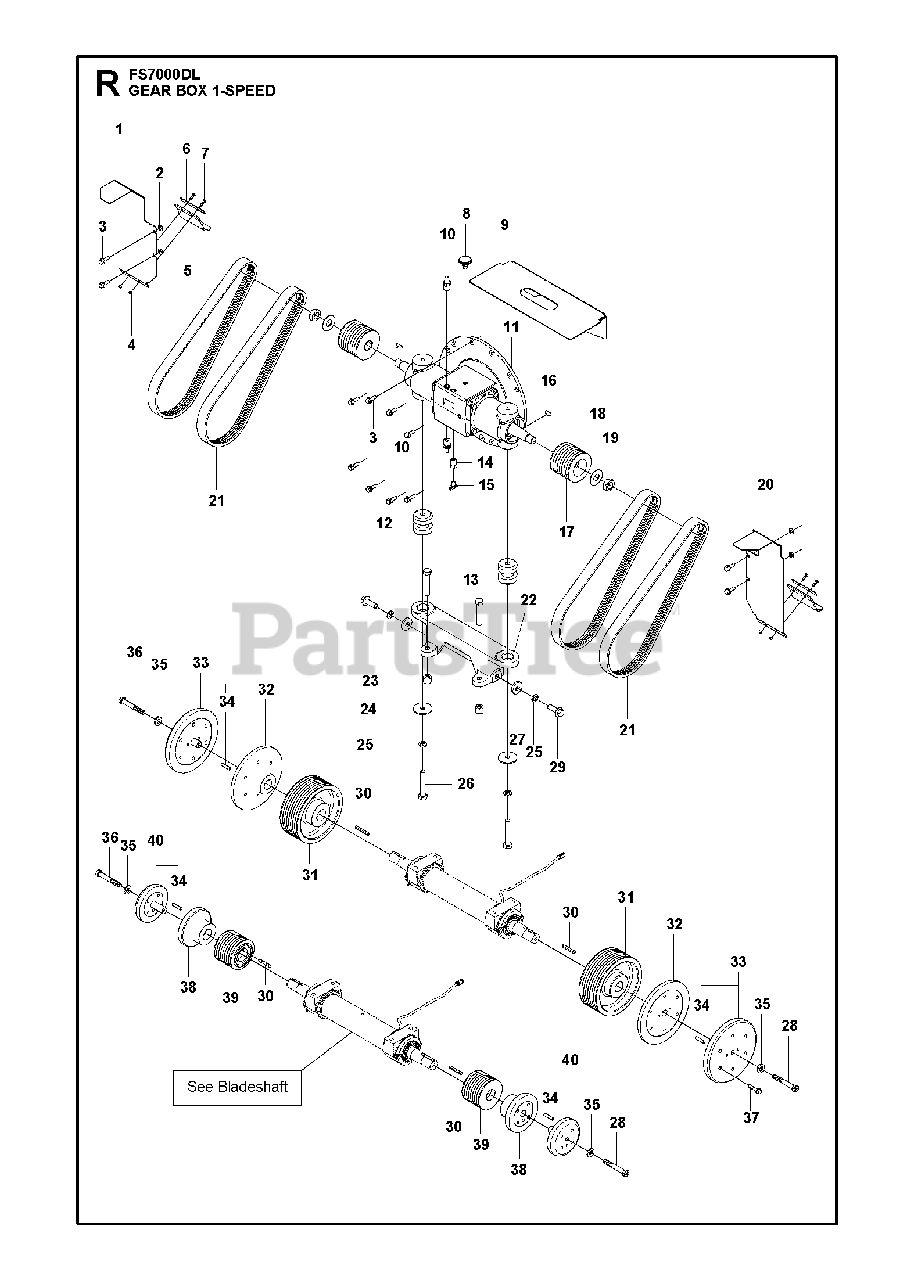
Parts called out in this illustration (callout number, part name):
2	WASHER
4	HEXAGON LOCKING NUT
12	ANTIVIBRATION ELEMENT
21	V-BELT26”, 30”
28	SCREW26”, 30”, 36”
33	FLANGE60" Including Pin"
36	SCREW26”, 30”, 36”
38	FLANGE26”, 30”
40	FLANGE36" Including Pin"
40	FLANGE42" Including Pin"
40	FLANGE48" Including Pin"
